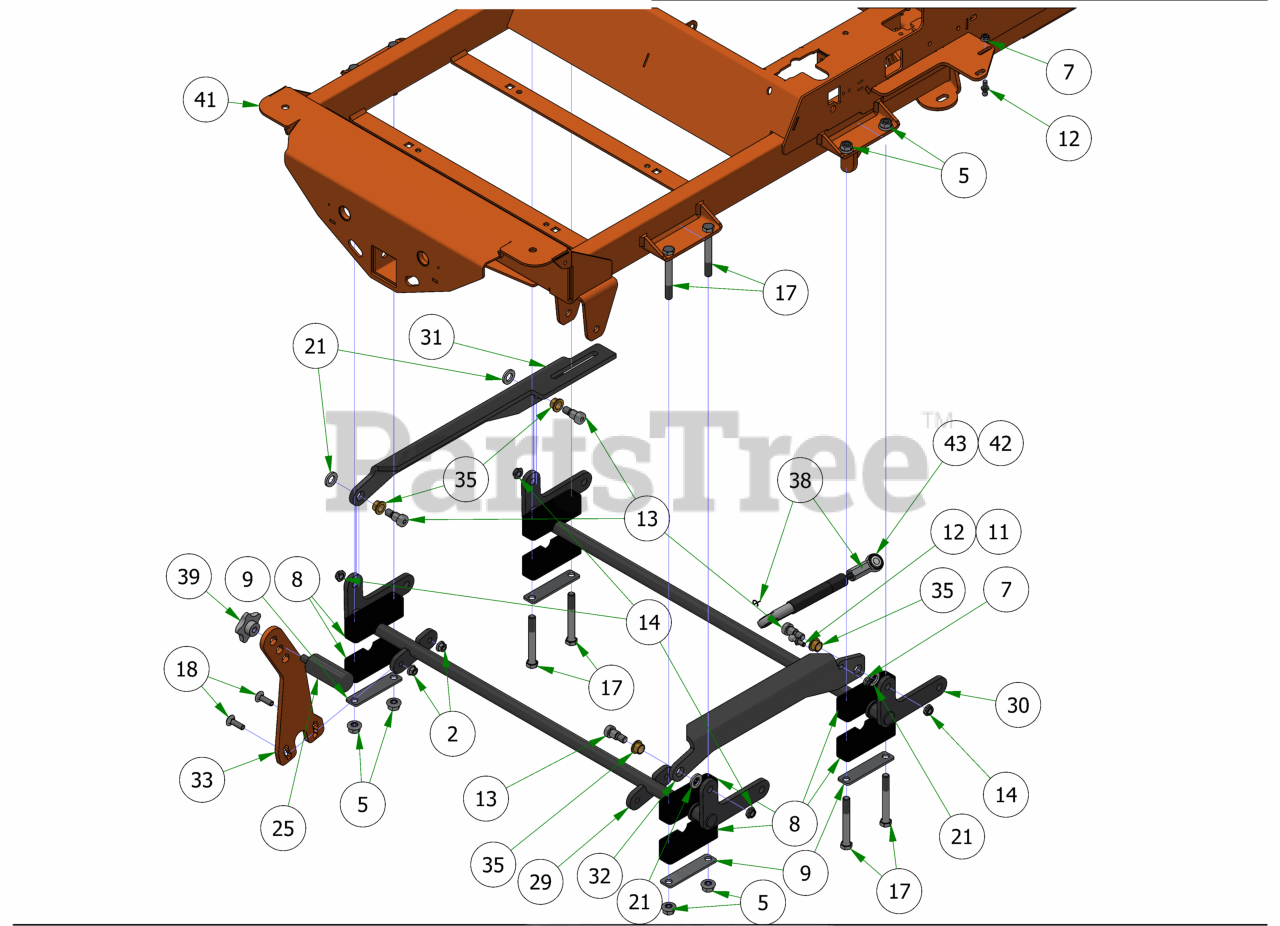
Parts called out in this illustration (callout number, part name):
1	.625 ID x 1.250 OD x .062 THK F/W Nylon
2	3/8-16 NYLON INSERT FLANGE LOCKNUT (GR.F) ZINC
3	1/2-13 HEX SERRATED FLANGE NUT HARD/ZINC
4	1/2-13 HEX NUT ZINC
5	1/2-13 NYLON INSERT FLANGE LOCKNUT ZINC
6	1/4-20 HEX SERRATED FLANGE NUT HARD/ZINC
7	5/16-18 HEX SERRATED FLANGE NUT HARD/ZINC
8	Two Piece Pillow Block
9	Two Piece Pillow Block Strap
10	2 1/2 x 1/2 Carriage Bolt
11	13mm Damper Ball Stud-Steering
12	10mm Damper Ball Stud-XP Linkage
13	5/8 X 5/8 SOCKET SHOULDER BOLT ZINC YELLOW
14	1/2-13 NYLON INSERT JAM LOCKNUT ZINC
15	3/8-24 Nylon Insert jam locknut
16	1/4-20 X 1-1/4 HEX CAP SCREW (GR.5) ZINC
17	1/2-13 X 4 HEX CAP SCREW (GR.8) ZINC YELLOW
18	3/8-16 X 1-1/4 CARRIAGE BOLT ZINC
19	.517 SQ WDTH ID X .937 OD X .060 THICK F/W PHOS/OIL
20	3/8 FLAT WASHER USS (1" OD) ZINC
21	.635 ID X 1.120 OD X .140 THICK FLAT WASHER NYLON
22	.505 ID X 1.000 OD X .125 THICK FLAT WASHER NYLON
23	5/8" Split Collar
24	MZ Deck Idler Spacer
25	Knurled Pedal
26	2019 Deck Height Cam
27	Dial Rod Plunger
28	2019 Outlaw Gen2 Dial Rod
29	2019 Outlaw Actuator - Front
30	2019 Outlaw Actuator - Rear
31	2019 Actuator Linkage – Right – Black
32	2019 Actuator Linkage - Left - Black
33	Foot Lift Upright Lever
34	2019 Outlaw Deck Travel Lock
35	.627 ID X .753 OD X .500 LGTH X 1.000 FLG OD X .094 FLG THICK FLANGED BEARING OIL-IMPREG BRNZ
36	Brake Spring
37	Seat Bracket Pin
38	Security Ring - PC744
39	Foot Pedal Knob 1/2-13
40	Travel Lock Rubber Grip
41	2019 Renegade Gas Frame - Powdercoated
42	250lb Gas Spring - 61" Deck
43	300lb Gas Spring - 72" Deck
